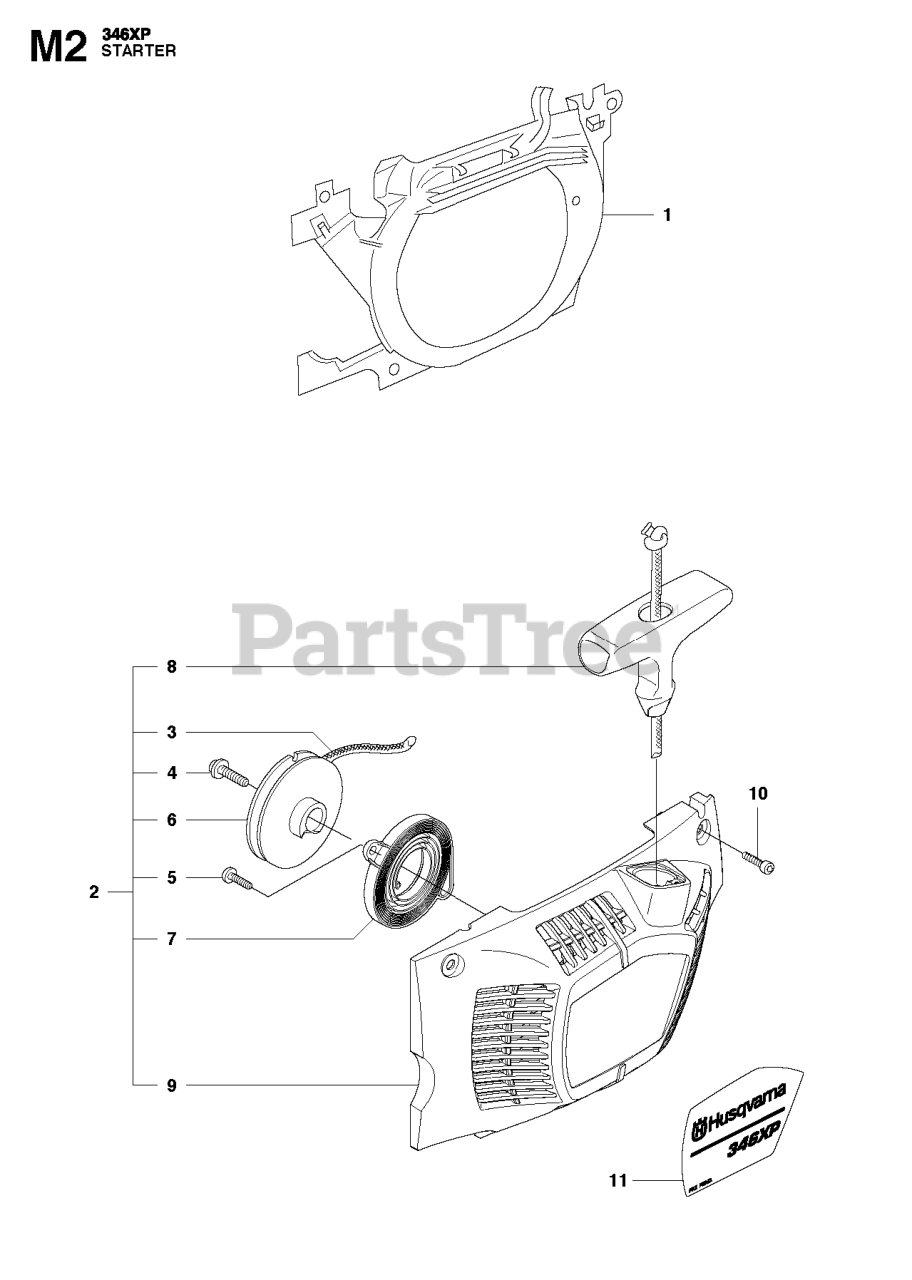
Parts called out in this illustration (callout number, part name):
1	Air Conductors
3	STARTER ROPE
6	STARTER PULLEY
7	STARTER SPRING
7	RETURN SPRING
9	STARTER HOUSING
10	SCREW.CIHPANMO M5X19 10.9
11	LABEL
